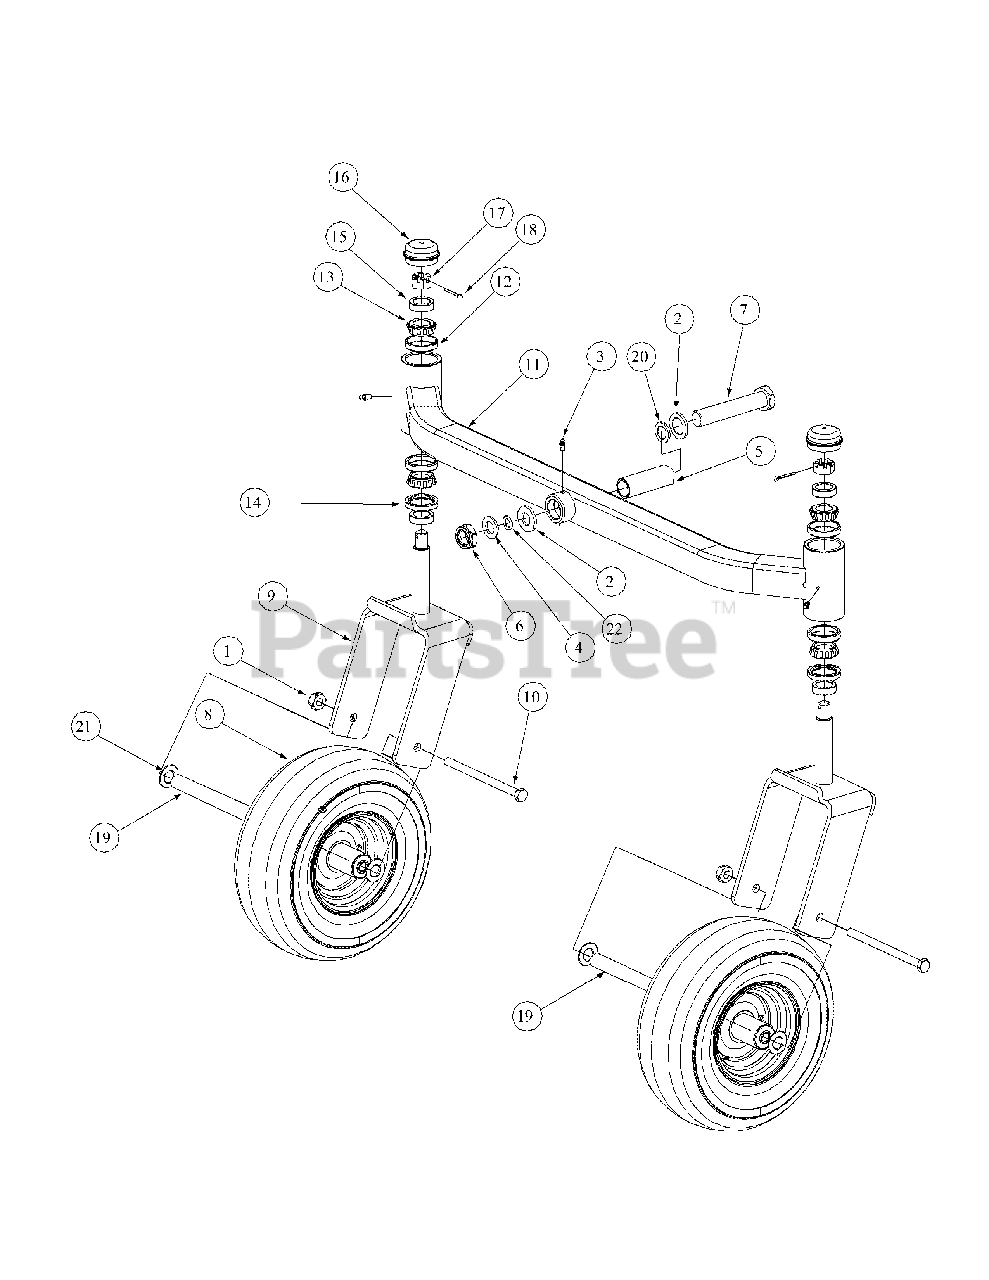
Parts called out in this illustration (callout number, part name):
1	Nut, 1/2-20, Center Lock
2	Bell Washer, 1.25 ID x 2.5 x .157
3	Grease Fitting, 1/4-28 x 3/16
4	Special Washer
5	Spacer, 1.005 ID x 1.25 OD x 3.6
6	Nut, Jam, 1.0-14, Insert Lock
7	Hex Cap Screw, 1-14 x 5.0
8	Wheel, 13 x 6.50 x 6, White includes:
8	Tire 13 x 6.50-6
8	Flange Bearing
8	Cage Roller Bearing
9	Yoke, Caster Wheel
10	HHCS, 1/2-20, 7.50
11	Front Axle Assembly
12	Cup Bearing
13	Bearing Cone
14	Seal
15	Ring Seal
16	Grease Cap, 1.986 OD
17	Slotted Nut, 3/4-16
18	Cotter Pin, 5/32, 1.25
19	Wheel Spacer
20	Flat Washer, 1.25 ID
21	Spacer, .812 ID x .218LG
22	Retainer Extension, Self Locking
